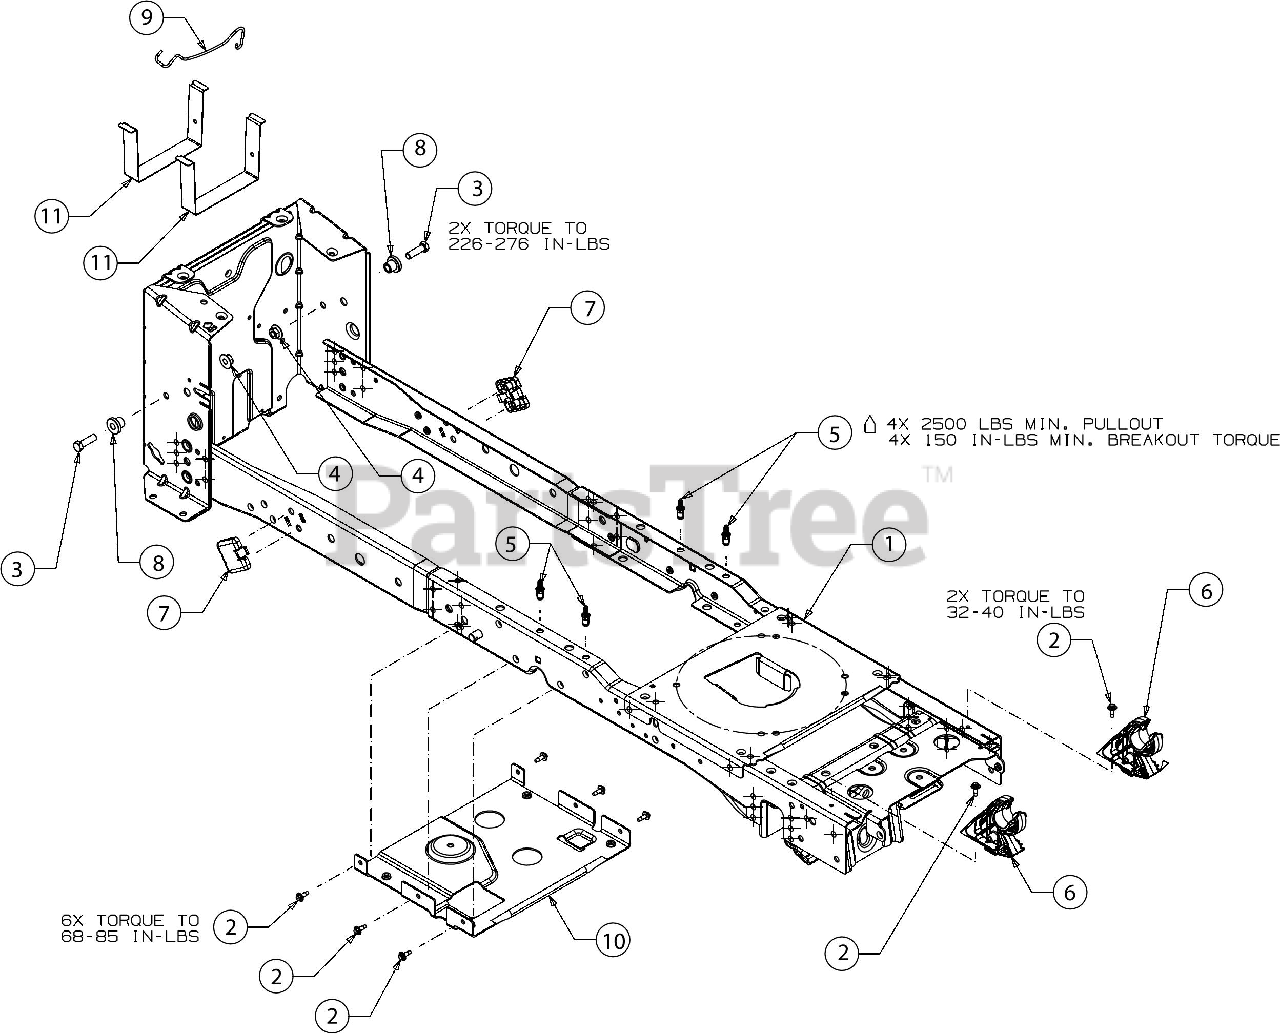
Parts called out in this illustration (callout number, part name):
1	FRAME ASSEMBLY
2	SCREW M6-1 X .625
3	SCREW 3/8-16 X 1.25 GR5
4	FLANGE LOCK NUT
5	RIVET-HEX STUD 1/4-20 FRM
6	HOOD PIVOT BRACKET
7	LIFT ROD WEAR PAD
8	SHOULDER SPACER
9	BATTERY HOLD DOWN ROD
10	FRAME BRACE BRACKET
11	BATTERY BRACKET
